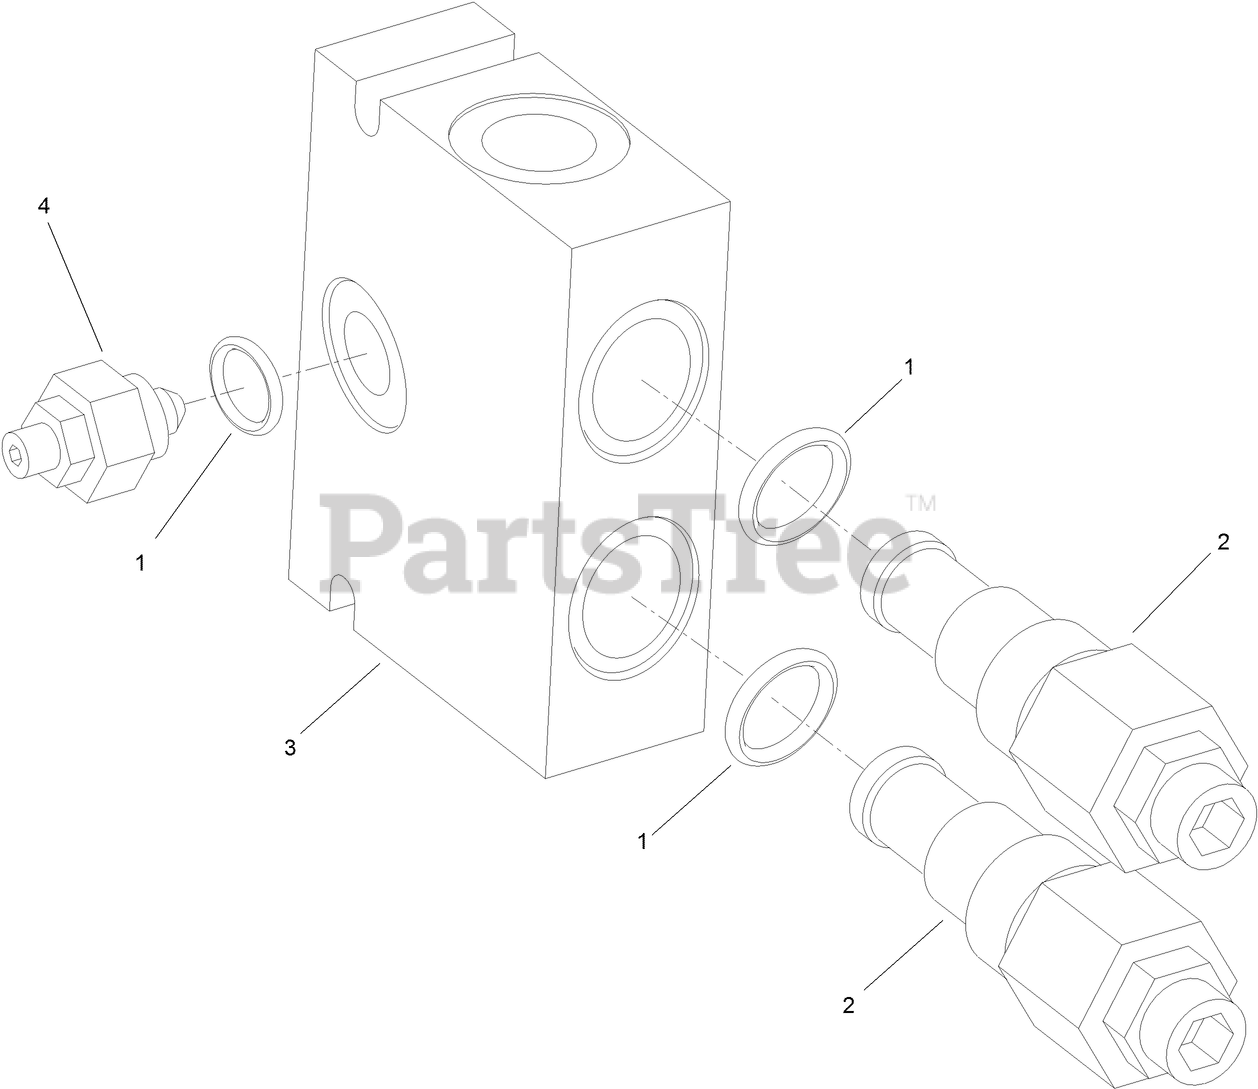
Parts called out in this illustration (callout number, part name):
1	SEAL KIT
2	VALVE-CARTRIDGE
3	MANIFOLD ASM
4	NEEDLE VALVE ASM
